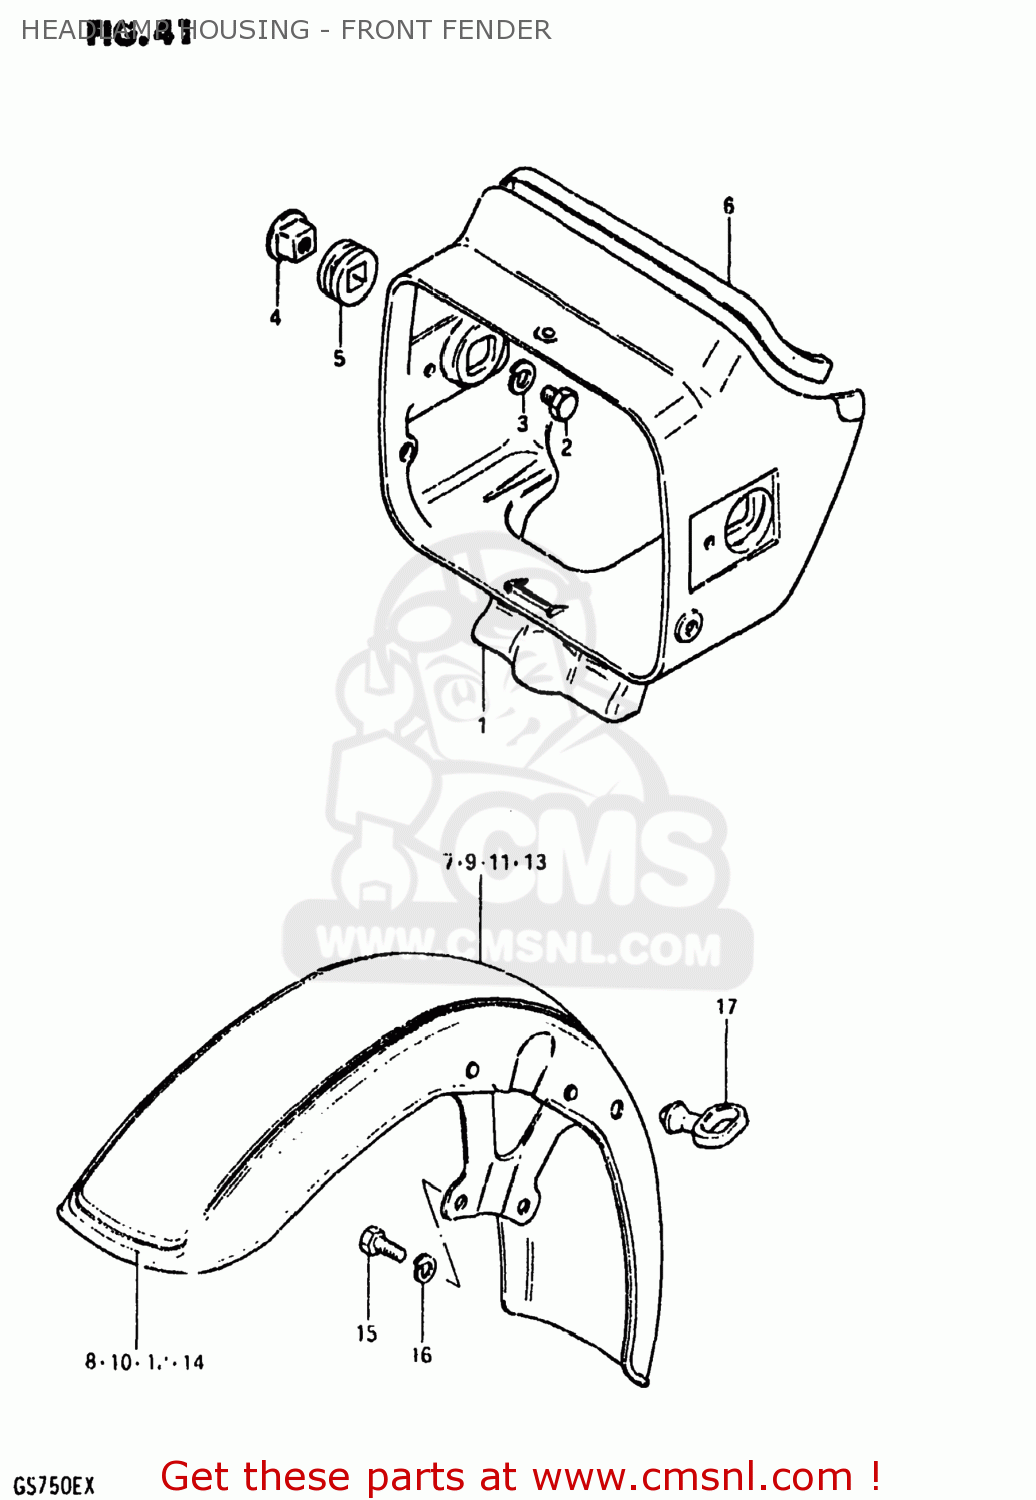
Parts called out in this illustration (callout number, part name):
1	HOUSING,HEADLAMP
2	BOLT
3	LOCK WASHER
4	SPACER,HEADLAMP HOUSING
5	CUSHION,HEADLAMP HOUSING
6	MOLDING,HEADLAMP HOUSING
7	FENDER,FRONT
8	TAPE,FRONT FENDER
9	FENDER,FRONT
10	TAPE,FRONT FENDER
11	FENDER,FRONT
12	TAPE,FRONT FENDER
13	FENDER,FRONT
14	TAPE,FRONT FENDER
15	BOLT
16	LOCK WASHER
17	GUIDE,CABLE
